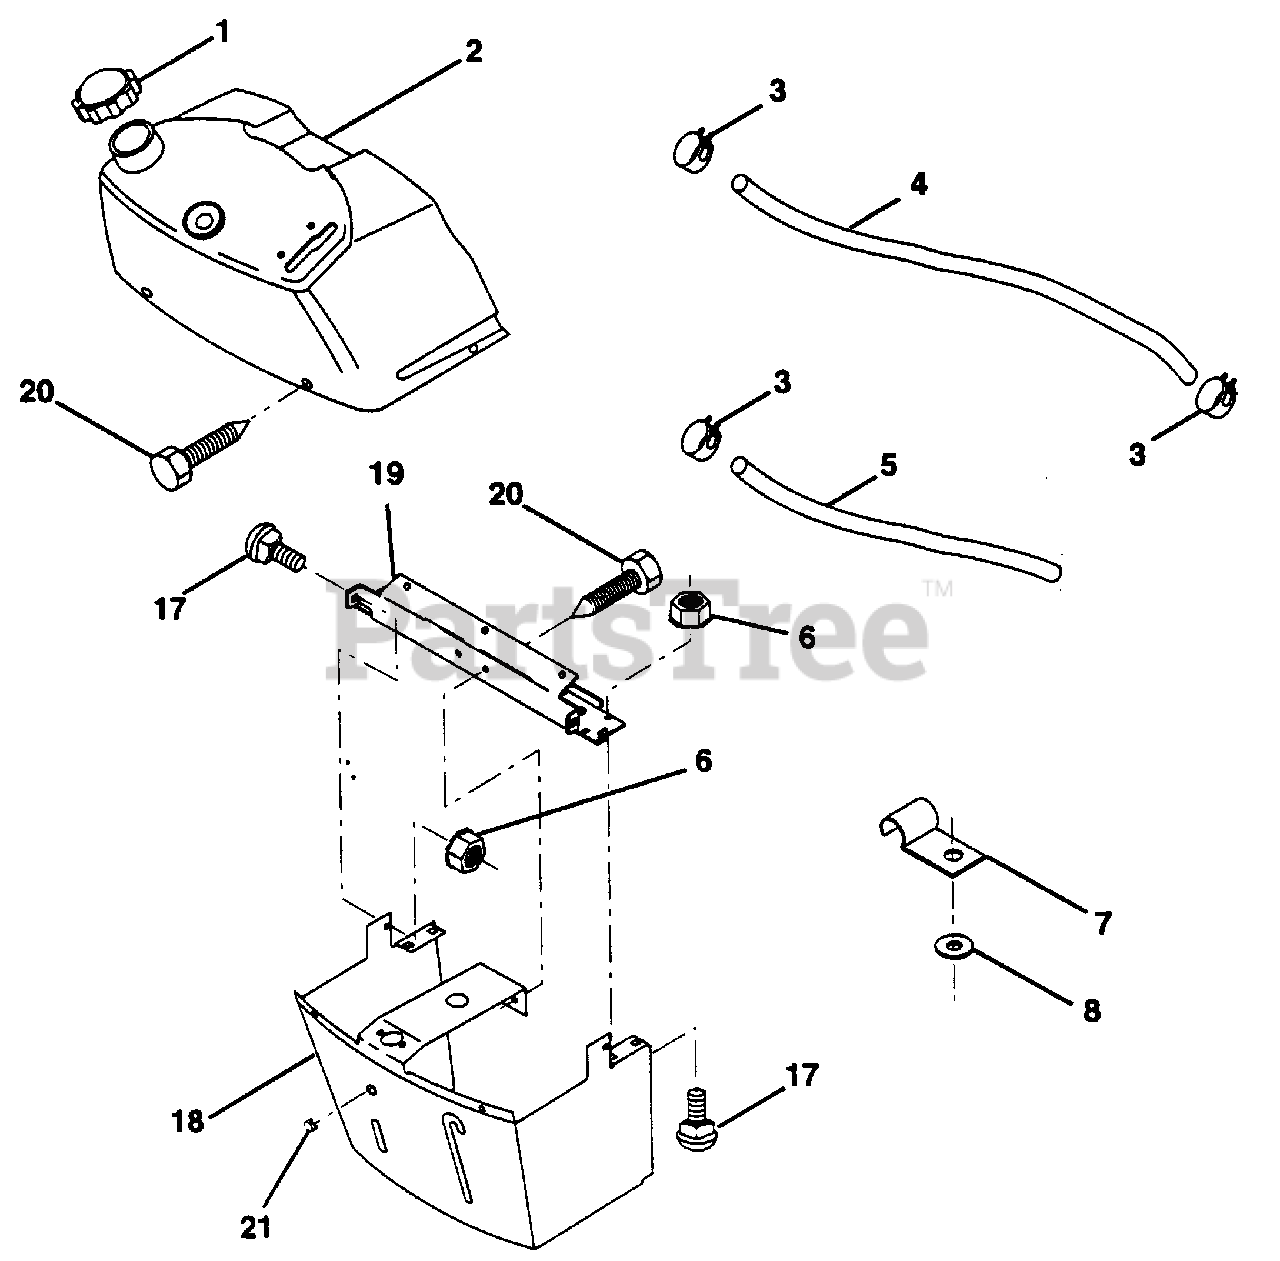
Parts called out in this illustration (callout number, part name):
1	Cap, Fuel Tank (AYP part number)
2	Assembly, Dash & Fuel Tank (AYP part number)
3	Clamp, Hose (AYP part number)
4	Line, Fuel (AYP part number)
5	Line, Fuel (AYP part number)
6	Nut, Hex, Keps 1/4-20 (AYP part number)
7	Clip, Fuel Line (AYP part number)
8	Washer 9/32 x 3/4 x 16 Gauge (AYP part number)
17	Bolt, Carriage 1/4-20 x 1/2 Grade 5 (AYP part number)
18	Support Assembly, Dash (AYP part number)
19	Brace, Cross (AYP part number)
20	Screw, Self-Tapping 1/4-20 x 1/2 (AYP part number)
21	Plug, Dome, Black (AYP part number)
